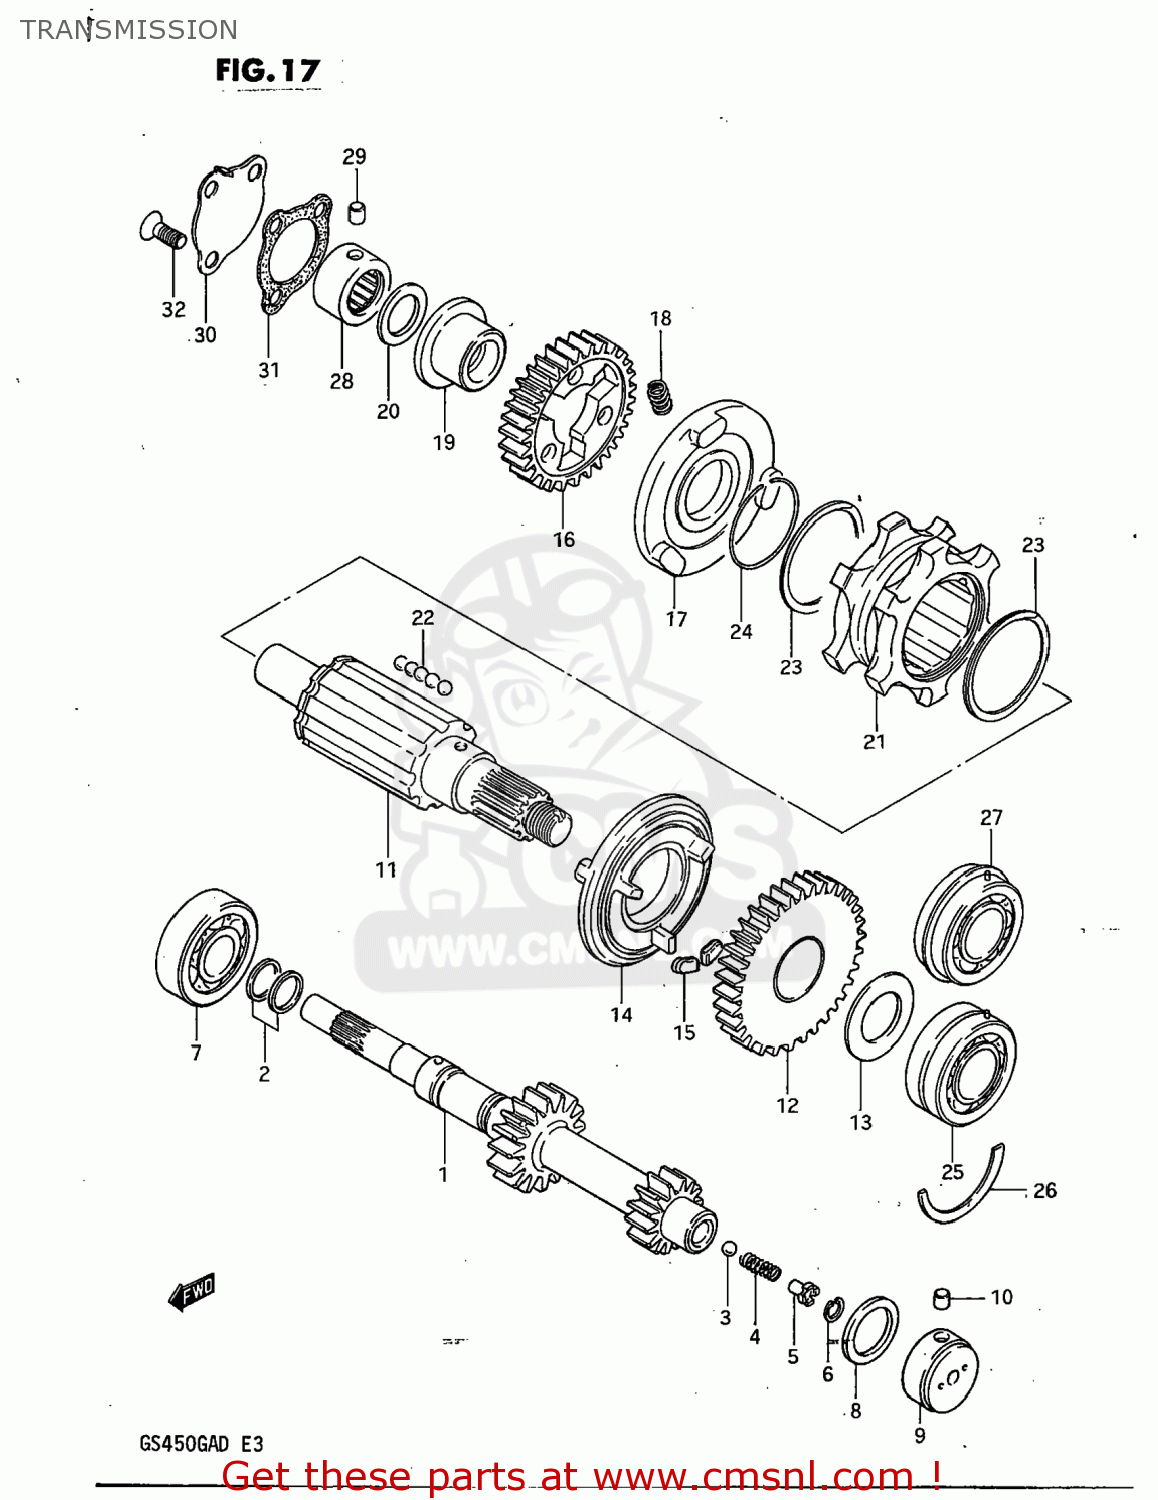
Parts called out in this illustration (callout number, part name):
1	SHAFT,COUNTER
3	BALL
4	SPRING
6	CIRCLIP
7	BEARING
9	ROLLER BEARING (20X34X2
10	PIN
11	SHAFT,DRIVE
12	GEAR,FIRST DRIVEN
13	WASHER
14	BUSHING,FIRST DRIVEN GEAR
15	DAMPER,FIRST DRIVEN
16	GEAR,SECOND DRIVEN
17	DOG PLATE,SECOND DRIVEN
18	SPRING
19	BUSHING
21	SLIDING DOG
22	BALL
23	CIRCLIP
24	CIRCLIP
25	BEARING
26	C RING
27	BALL BEARING 25X52X21
28	BEARING(20X34X16)
29	PIN
30	PLATE,COUNTERSHAFT BEARING
31	GASKET,DRIVESHAFT BEARING RIGHT,TOP
32	SCREW
